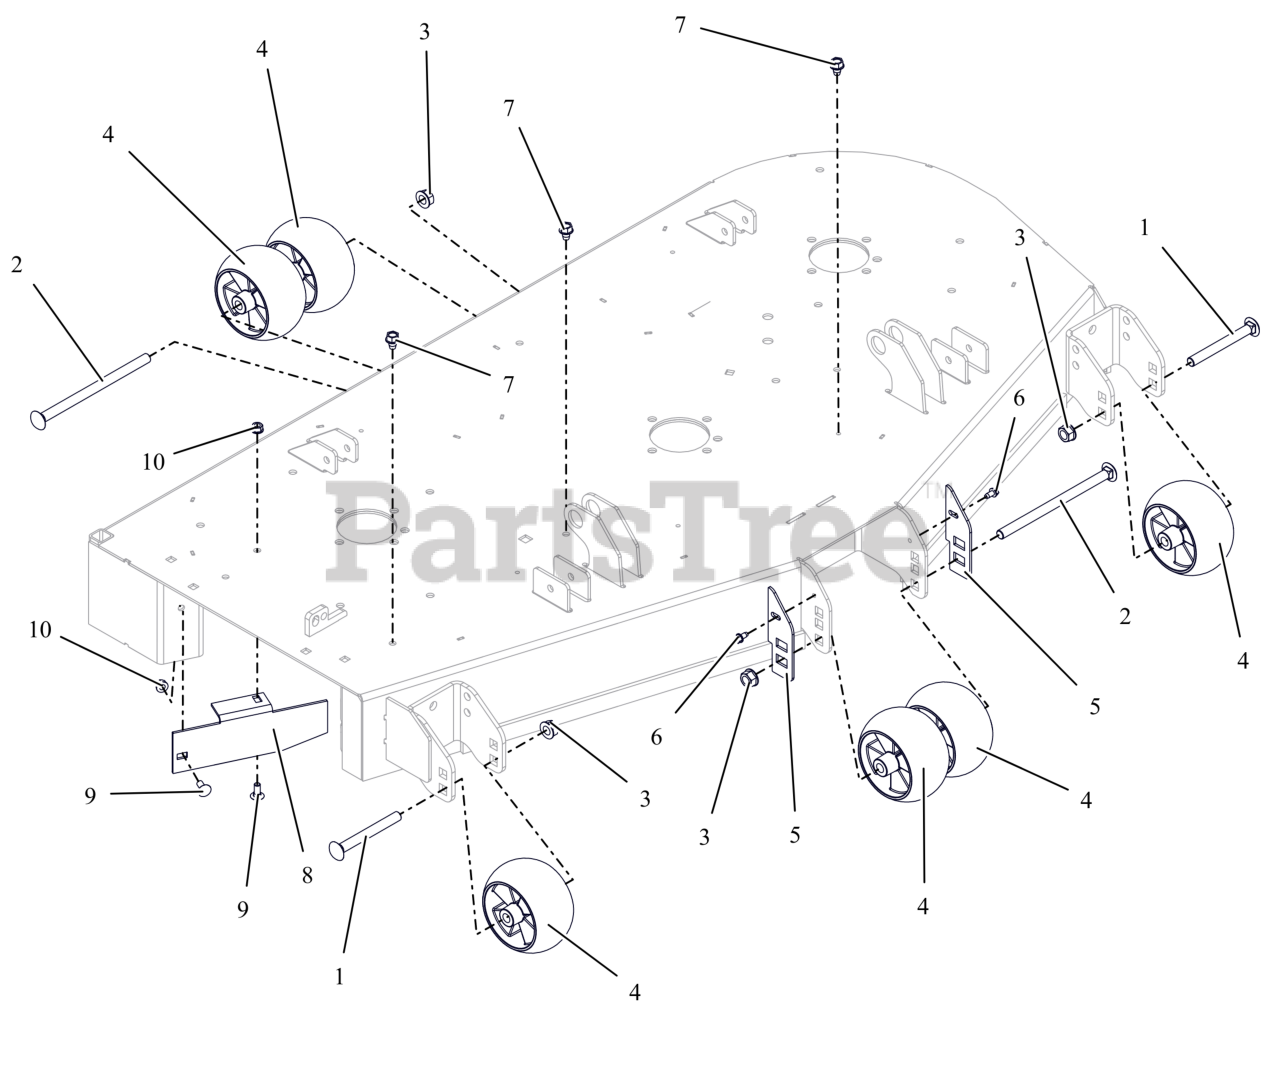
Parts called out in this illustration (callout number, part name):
1	BLT-RHNS .50-13X4.50 G5 ZCC NS
2	BLT-RHSN .50-13X8.00 G5 ZCC NS
3	NUT-LK-CTR-FLG .500-13 GG ZCC
4	WHEEL, ANTI SCALP - 5X3 CTR W/RIBS
5	PLATE, ANTI SCALP WHEEL 60" (ORANGE)
6	SCR-TAP .25-20X.50 HWH ZCC
7	SCR,TAP .375-16X.50 HWH TR ZCC
8	BAFFLE, DISCHARGE, 52"
9	BLT,RHSN .31-18X.75 G5 ZCC
10	NUT,LK-CTR-FLG .31-18 GF ZCC
